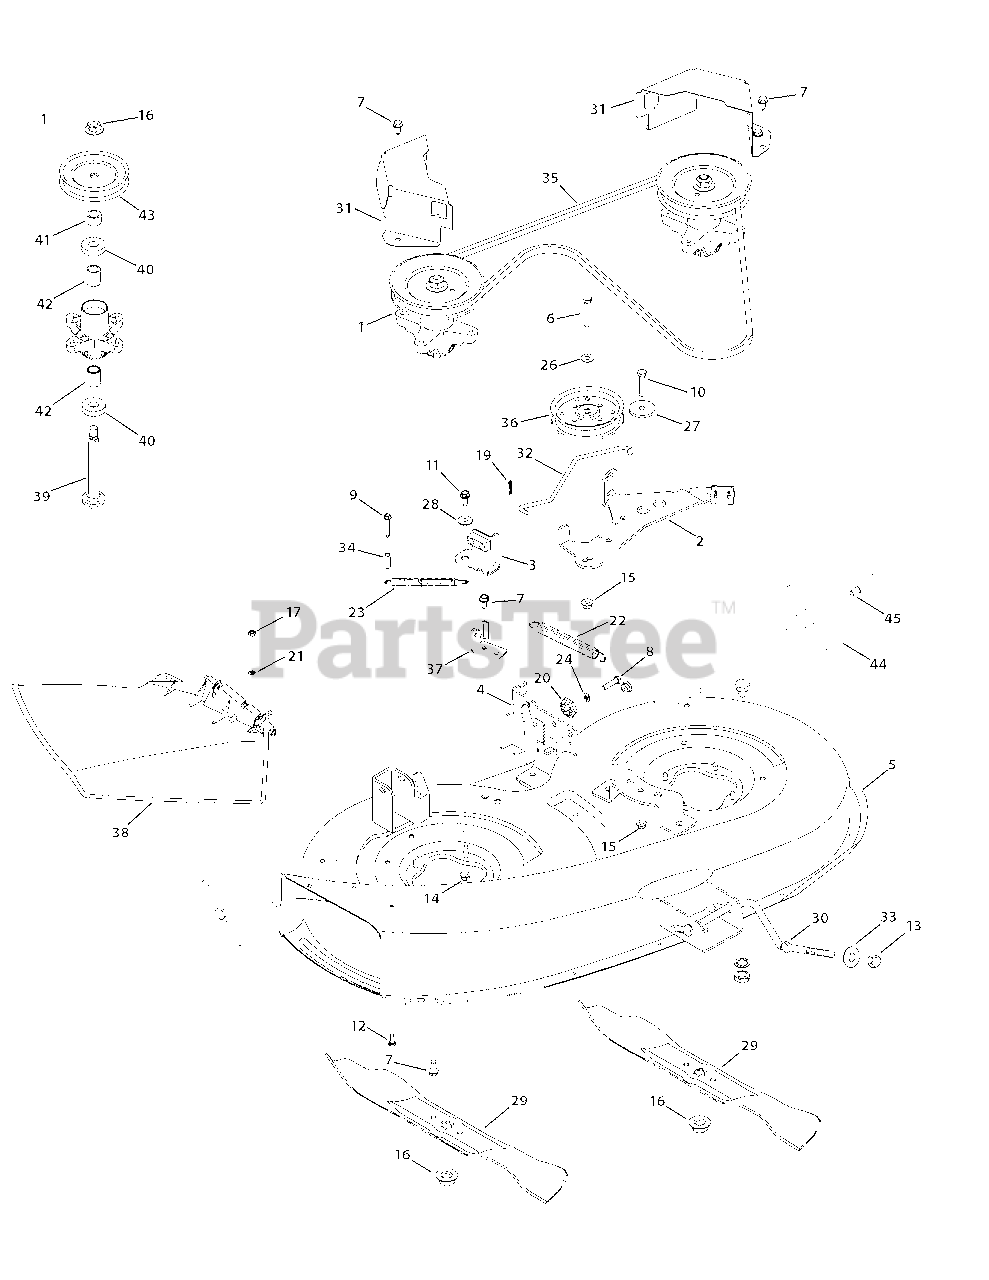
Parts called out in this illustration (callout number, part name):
1	Pulley Spindle Ass’y 5.75 dia.
2	Deck Brake Assembly
6	Hex Screw 3/8-16 x 1.75
7	S-Tapp Screw 5/16-18 x .75
8	Hex Wash Tap Screw 5/16-18 x 1.25
9	Hex Wash HD Bolt 1/4-20 x 1.50" Lg.
10	Hex Bolt 3/8-16 x 1.25
11	Hex Bolt 5/16-18 x .75" Lg. Gr. 5
12	Hex Bolt 1/4-20 x .62 Gr. 5
13	Flexloc Nut 1/2-13
14	Hex Flange Locknut 5/16-18 Gr. F, Nylon
15	Hex Flange Locknut 3/8-16 Gr. F Nylon
16	Hex Flange Locknut 5/8-18
17	Hex L-Flanged Nut 1/4-20 Gr. F Nylon
19	Int. Cotter Pin .072 x 1.13" Lg.
20	Deck Adjustment Gear
21	Bolt Retainer 1/4" x .50" OD
22	Extension Spring .75 dia. x 6.37 Lg.
23	Extension Spring .50 dia x 6.37
24	L-Wash 5/16 ID
26	Flat Washer
27	Shoulder Spacer .8540 x .200
28	Shoulder Spacer
29	3 in 1 Blade 19.38" Lg.
30	Deck Rod, Front Adjustable
32	Brake Control Rod
33	Deck Lift Pivot Cup
34	Spacer .260 x .375 x 1.030 Lg.
36	Idler Pulley w/Flange 4.25 Dia
38	Side Discharge Chute Assembly
39	Spindle Shaft 5.5
40	Ball Bearing .787 ID x 1.85 OD x .551
41	Spacer, .820 x 1.150 x .480
42	Spacer .80 x 1.10 x 1.322
45	Shoulder Bolt .498 Dia x 1.53 x 3/8-16
